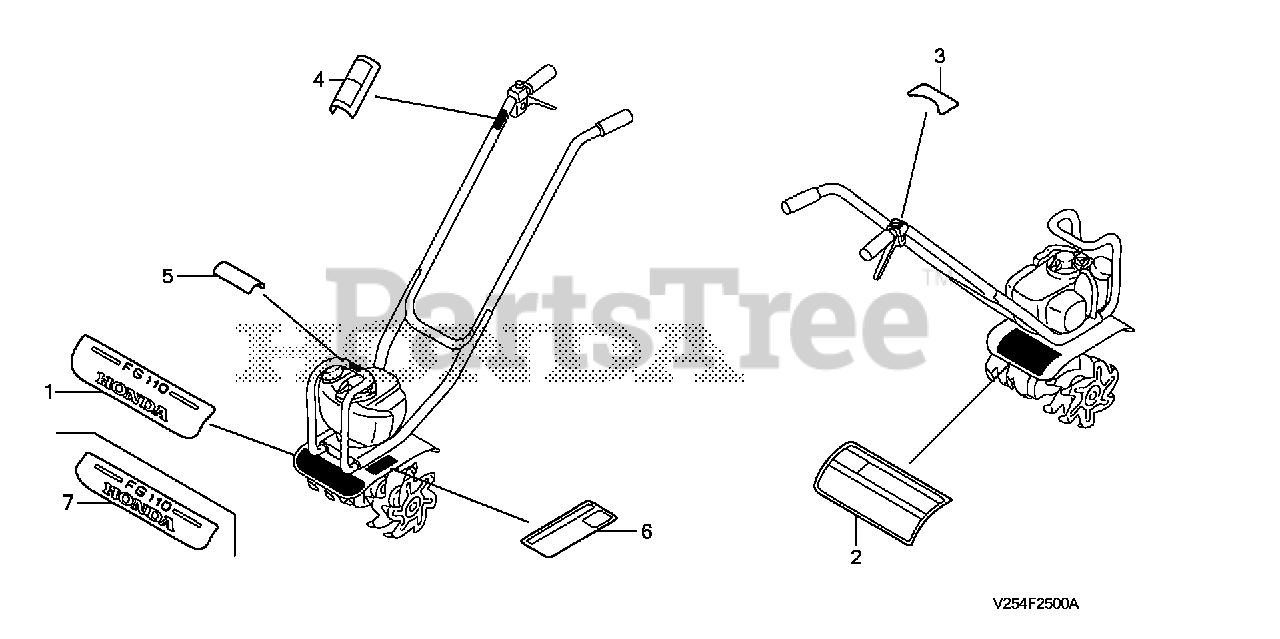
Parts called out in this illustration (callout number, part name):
1	MARK, STRIPE
2	LABEL, TINE DANGER (ENGLISH)
3	MARK, ENGINE SWITCH INDICATION (ENGLISH)
4	MARK, CLUTCH INDICATION (ENGLISH)
5	MARK, HOLD POSITION (ENGLISH)
6	MARK, OIL LEVEL CHECK (ENGLISH)
